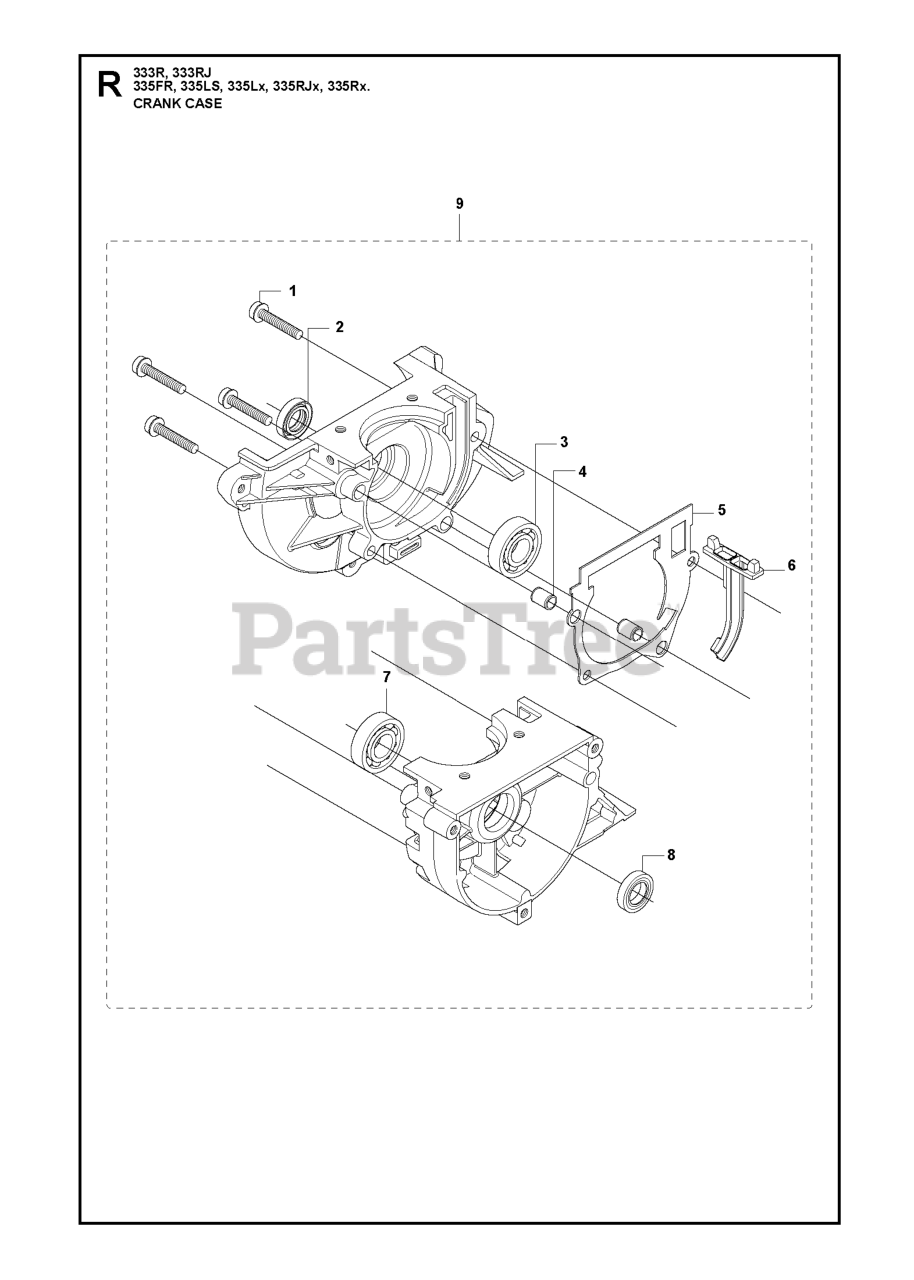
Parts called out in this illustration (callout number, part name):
2	SEALING RING
3	BALL BEARING
5	GASKET CRANKCASE
6	INSERT, CARTER
7	BALL BEARING
8	SEALING RING
9	CRANKCASE CPL
